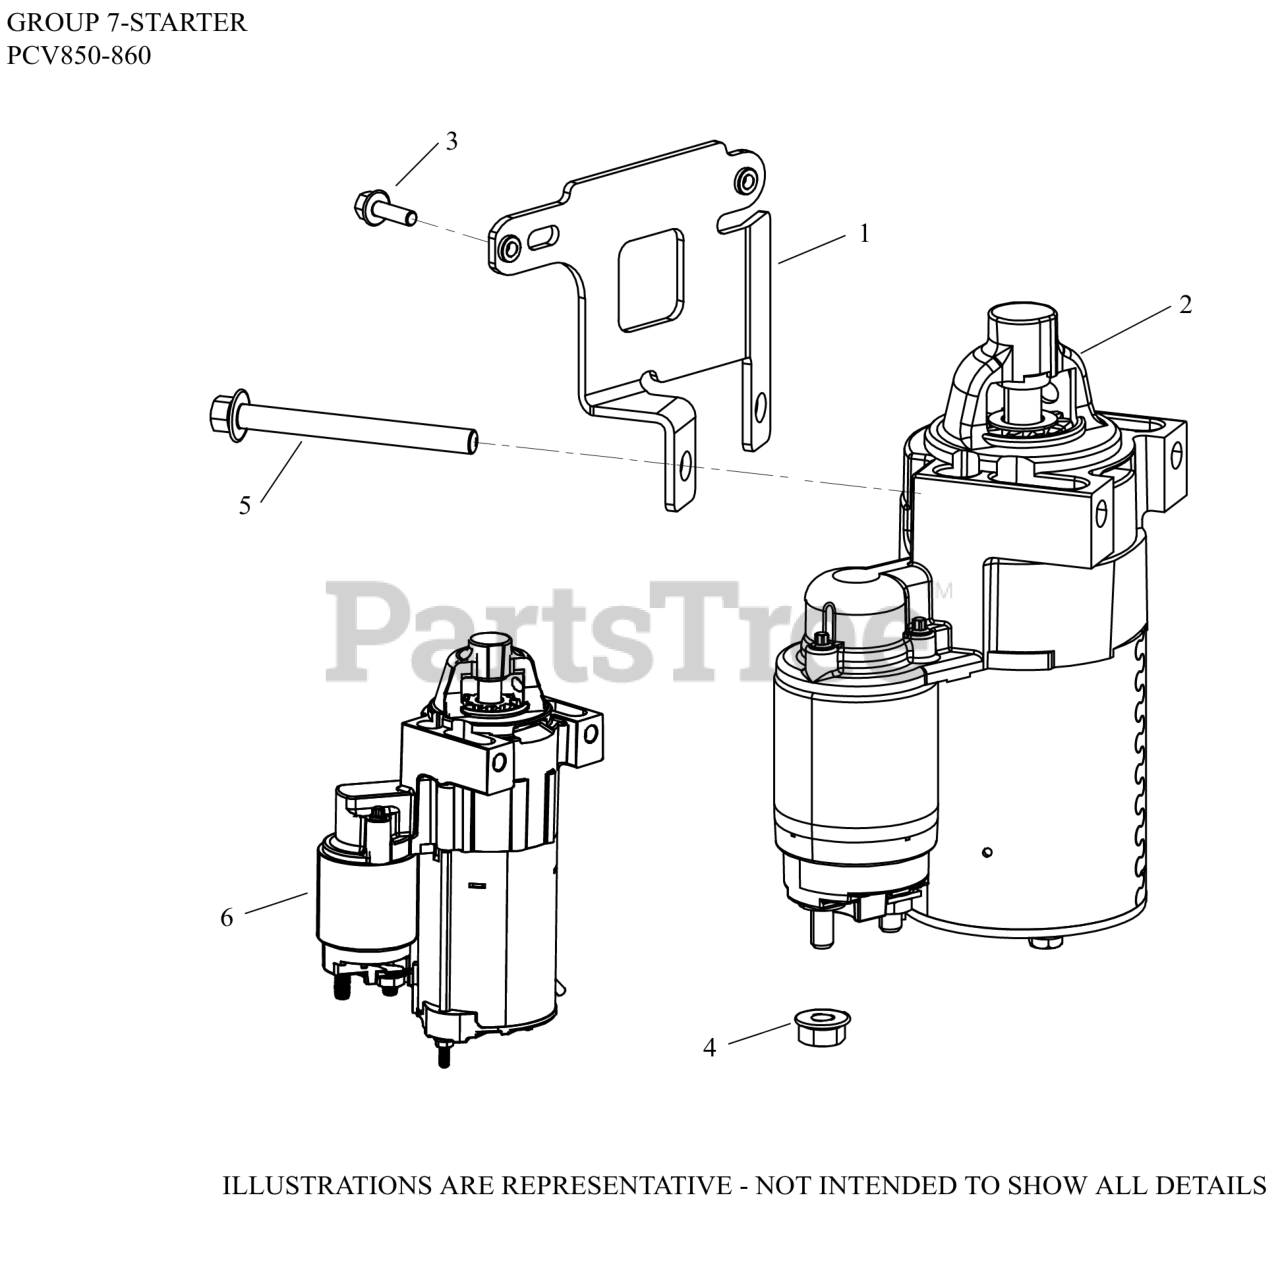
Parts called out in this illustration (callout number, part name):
1	BRACKET, ECU
2	STARTER, SOLENOID SHIFT-(#2509824S)
3	SCREW, HVY FLG M5X.8X16
4	NUT, FLG M8X1.25
5	SCREW, FLG M8X1.25X80
